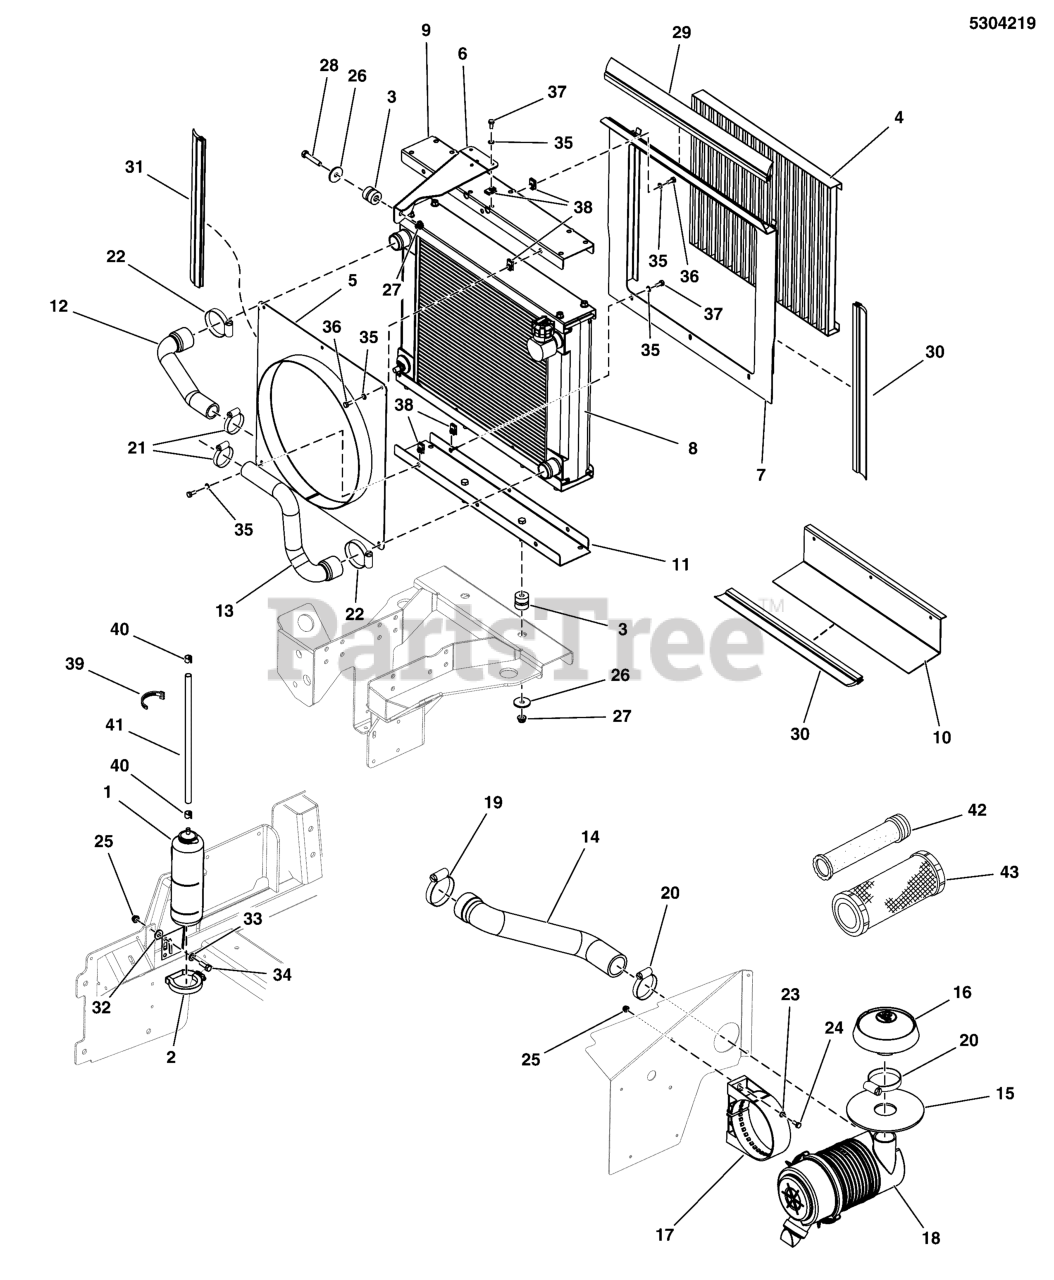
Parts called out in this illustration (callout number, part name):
1	BOTTLE, COOLANT OVERFLOW
2	CLAMP, COOLANT OVERFLOW
3	MOUNT, ISO, BOTTOM, RAD 5000Z-DIESEL
4	SCREEN, RADIATOR, IS2600Z
5	WELD, FAN SHROUD, IS2600Z - BLK
6	PLATE, UPPER RADIATOR MOUNT,IS2600 - BLK
7	WELD, SCREEN MOUNT - BLK
8	RADIATOR, .993 YANMAR ENGINE, 3TNM74F
9	BRACKET, RADIATOR, TOP - BLK
10	PLATE, LOWER SEAL MOUNT, IS2600 - BLK
11	WELD, BRKT, RAD, LOWER, 2600 - BLK
12	HOSE, RAD, UPPER, IS2600
13	HOSE, RAD, LOWER, IS2600
14	HOSE, AIR FILTER, IS2600Z
15	GUARD, AIR FILTER, IS2600
16	CAP, RAIN ASSY
17	BRACKET, AIR CLEANER ASSY
18	AIR CLEANER ASSY
19	CLAMP, SS HOSE 2-3/4
20	CLAMP, SS, HOSE, 2-1/2"
21	CLAMP, SS HOSE, 1-3/4
22	CLAMP, SS, HOSE, 2-1/4"
23	WASHER, 5/16 F436 FLAT
24	BOLT, 5/16-18 X 1-1/4 GD5 CZ
25	NUT, 5/16-18 HEX NYLOCK FLANGE
26	WASHER, .390 X 1.50 X .109, CZ
27	NUT, 3/8-16 HEX NYLOCK FLANGE
28	BOLT, 3/8-16 X 2, GD5, CZ
29	SEAL, WIPER, CLIP ON, 21.50
30	SEAL, WIPER, CLIP ON, 18.50
31	SEAL, WIPER, CLIP ON, 16.00
32	WASHER, 5/16 USS
33	WASHER, 5/16" SAE
34	BOLT, 5/16-18 X 1 GD5 CZ
35	WASHER, 1/4 SAE
36	HHCS, 1/4-20 X 0.625, GR5, ZINC/CLEAR
37	BOLT, 1/4-20 X 3/4 GD5 CZ
38	BODY CLIP, 1/4-20 X 1/2 DEEP
39	TIE, SELF-LOCKING, 12"
40	CLAMP, HOSE, EXTERNAL, 1/2 - RED
41	HOSE, RADIATOR TO OVERFLOW BOTTLE
42	ELEMENT ASSEMBLY
43	ELEMENT ASSY
